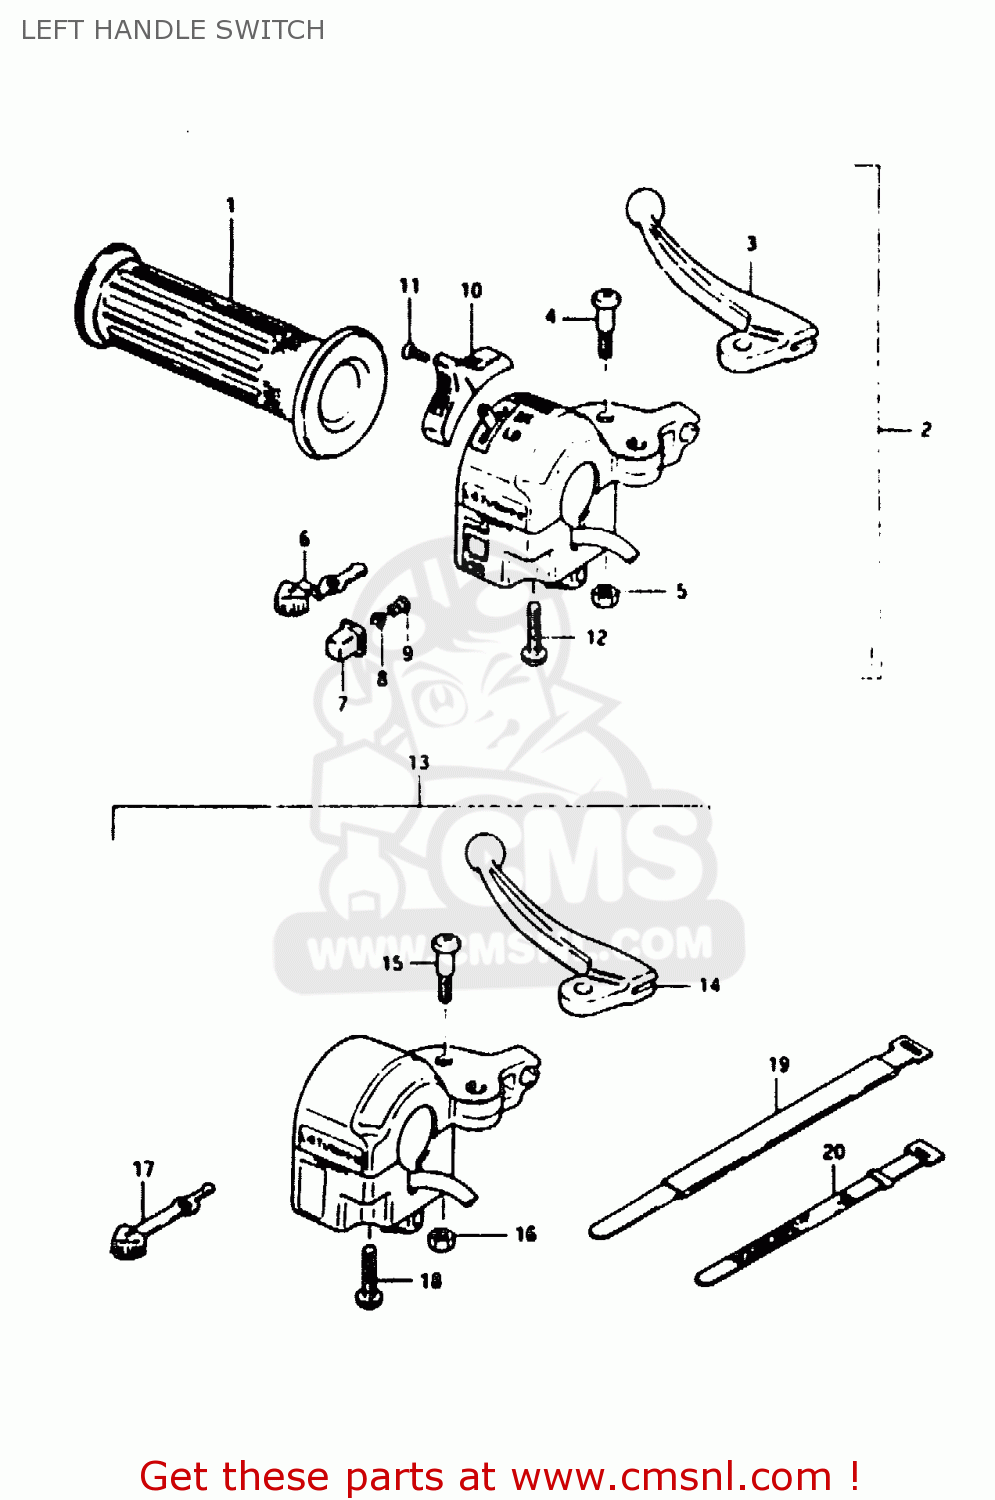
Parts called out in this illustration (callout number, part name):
1	GRIP,L
2	LEVER ASSY,CLUTCH
3	LEVER
4	BOLT,LEVER
5	NUT,LEVER BOLT
6	KNOB,TURN SIGNAL SWITCH
7	BUTTON,HORN
8	CONTACT
9	SPRING
10	KNOB
11	SCREW 3X6
12	SCREW 5X20
19	CLAMP
20	CLAMP(L:120)
